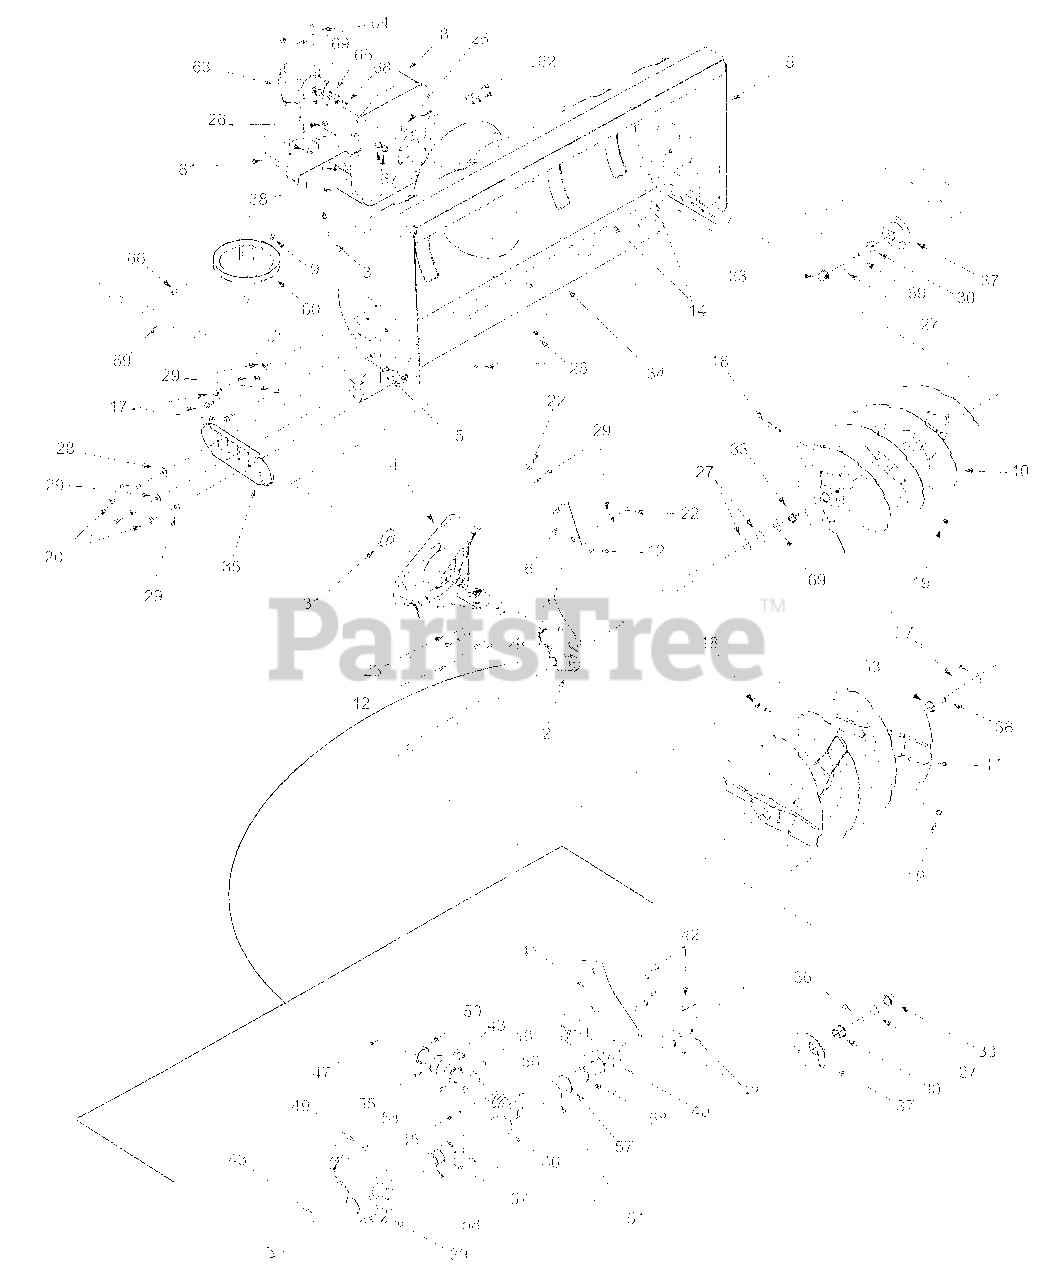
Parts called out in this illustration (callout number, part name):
2	Auger Gear Case
3	Belt Keeper Rod
14	Carriage Bolt, 5/16-18 x .62
15	Splined Carriage Screw, 5/16-18 x 1.0
17	Self Tapping Screw, 5/16-18 x .625
18	Shear Bolt, 5/16-18 x 1.5
19	Hex Lock Nut, 5/16-18
20	Hex Nut, 5/16-18
22	Hex Nut, 5/16-24
23	Spirol Pin, 1/4 x 1-1/2
26	Flange Lock Nut, 5/16-18
27	Flat Washer, .76 x 1.49 x .06
28	Flat Washer, .344 x 1.125 x .12
29	Bell Washer, .340 x .872
30	Hex Flange Bearing, .75 ID
31	Flange Ball Bearing, .75 x 1.85
33	Flange Bushing, .80 x .91
36	Spacer, .75 2 x .5
39	RH Reducer Housing
40	LH Reducer Housing
42	Self Tapping Screw, 1/4-20 x .75
43	Spiral Axle, 41.5"
45	Spring Spirol Pin, .25 x 1.25
46	Worm Gear, 20-tooth
47	Worm Shaft
48	Thrust Collar
49	Grease Plug
50	Grease Seal
51	Flat Washer, .76 x 1.5 x .030
54	Thrust Bearing, .75 x 1.25 x .078
55	Flange Bearing, .75 x 1.0 x .59
56	Flange Bearing, .503 x .75
57	Flange Bearing, .754 x 1.0 x .925
58	Grease Seal
59	Lower V-belt
60	Drive Pulley, 7"
61	Drive Mounting Bracket
62	Hex Cap Screw, 3/8-16 x .75
63	Right Angle Drive
64	Hex Cap Screw, 3/8-16 x 1.0
65	Coupling
66	Socket Head Cap Screw, 5/16-18 x 1.75
67	Flange Lock Nut, 3/8-16
68	Square Key, 3/16 x .75
69	Hi-pro Key, 3/16 x .75
